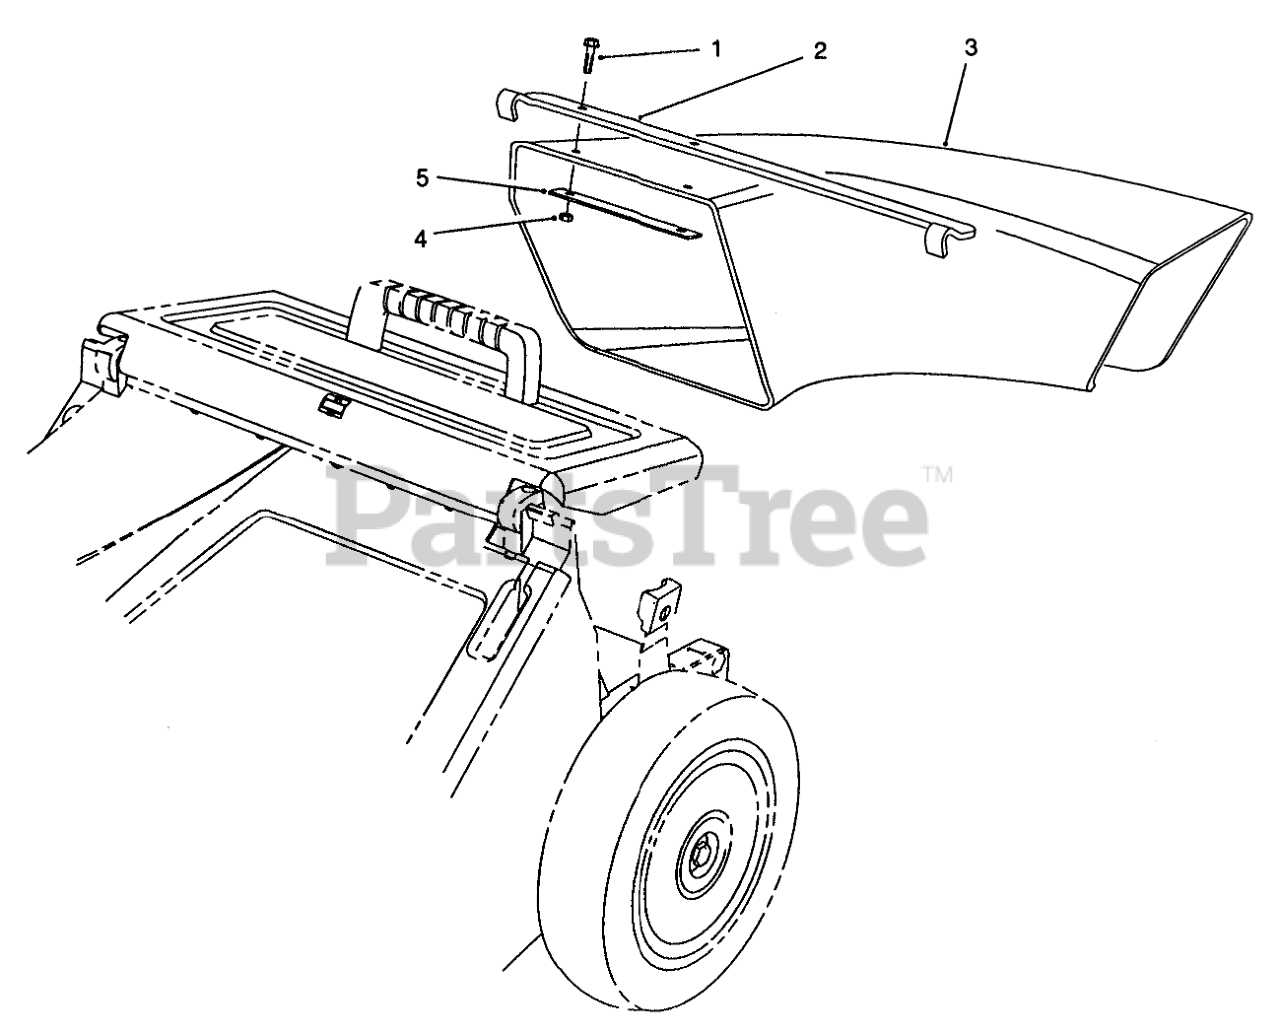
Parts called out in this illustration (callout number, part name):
1	SCREW-HWH
2	CHUTE HANGER BRACKET
3	Chute-Discharge
4	NUT-LOCK, NI
5	STRESS PLATE
